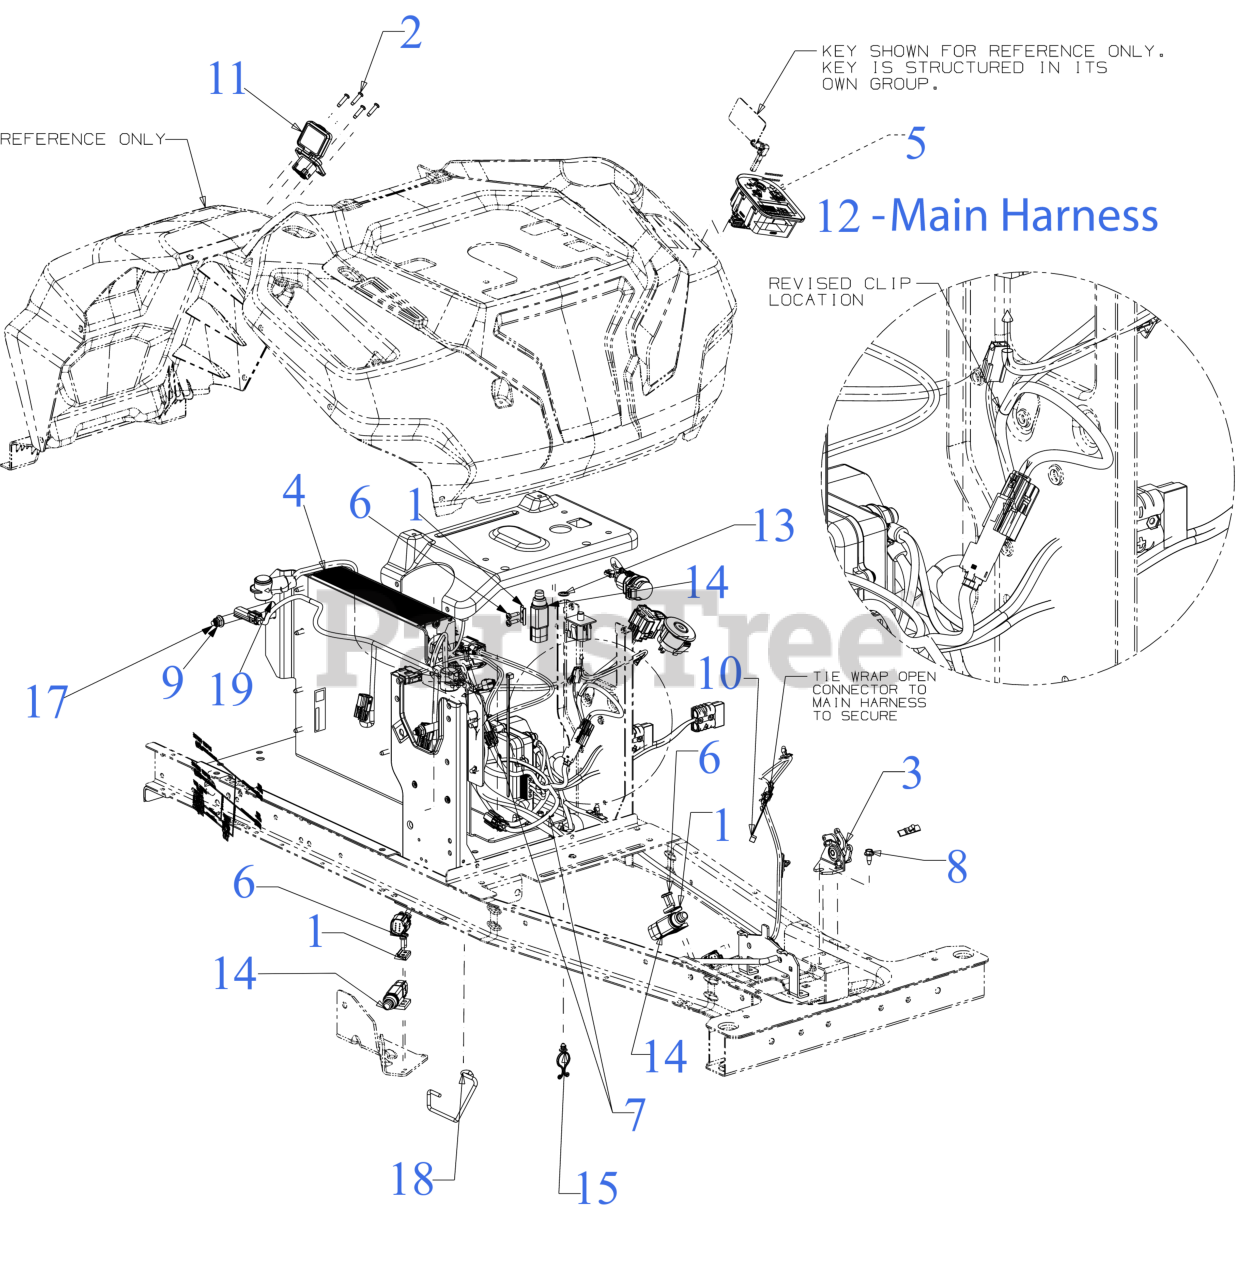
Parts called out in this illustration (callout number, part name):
1	PLATE-SWITCH
2	SCREW, #8-16X.750 PH
3	THROTTLE SENSOR ASSEMLBLY
4	Not Serviceable/ Components Only
5	SWITCH (VCM/UL/G2/NO HL)
5	SW:ASM:SVCM:ERIDER:NO HL
6	SCREW #10-24X11/16 T-25
7	SCREW M6-1 x .625
8	SCREW 1/4-20X.625
9	FLANGE LOCK NUT 5/16-18
10	7" CABLE TIE
11	CHARGER PORT HARNESS (8-PIN)
12	MAIN HARNESS (VCM/SPDM)
12	SEALED PLUNGER SWITCH
14	SEALED PLUNGER SWITCH
15	TWIST LOCK CLIP
17	BATTERY ROD 5/16-18
18	DECK CABLE SUPPORT ROD
19	SPACER .322 x .438 x 3.855
